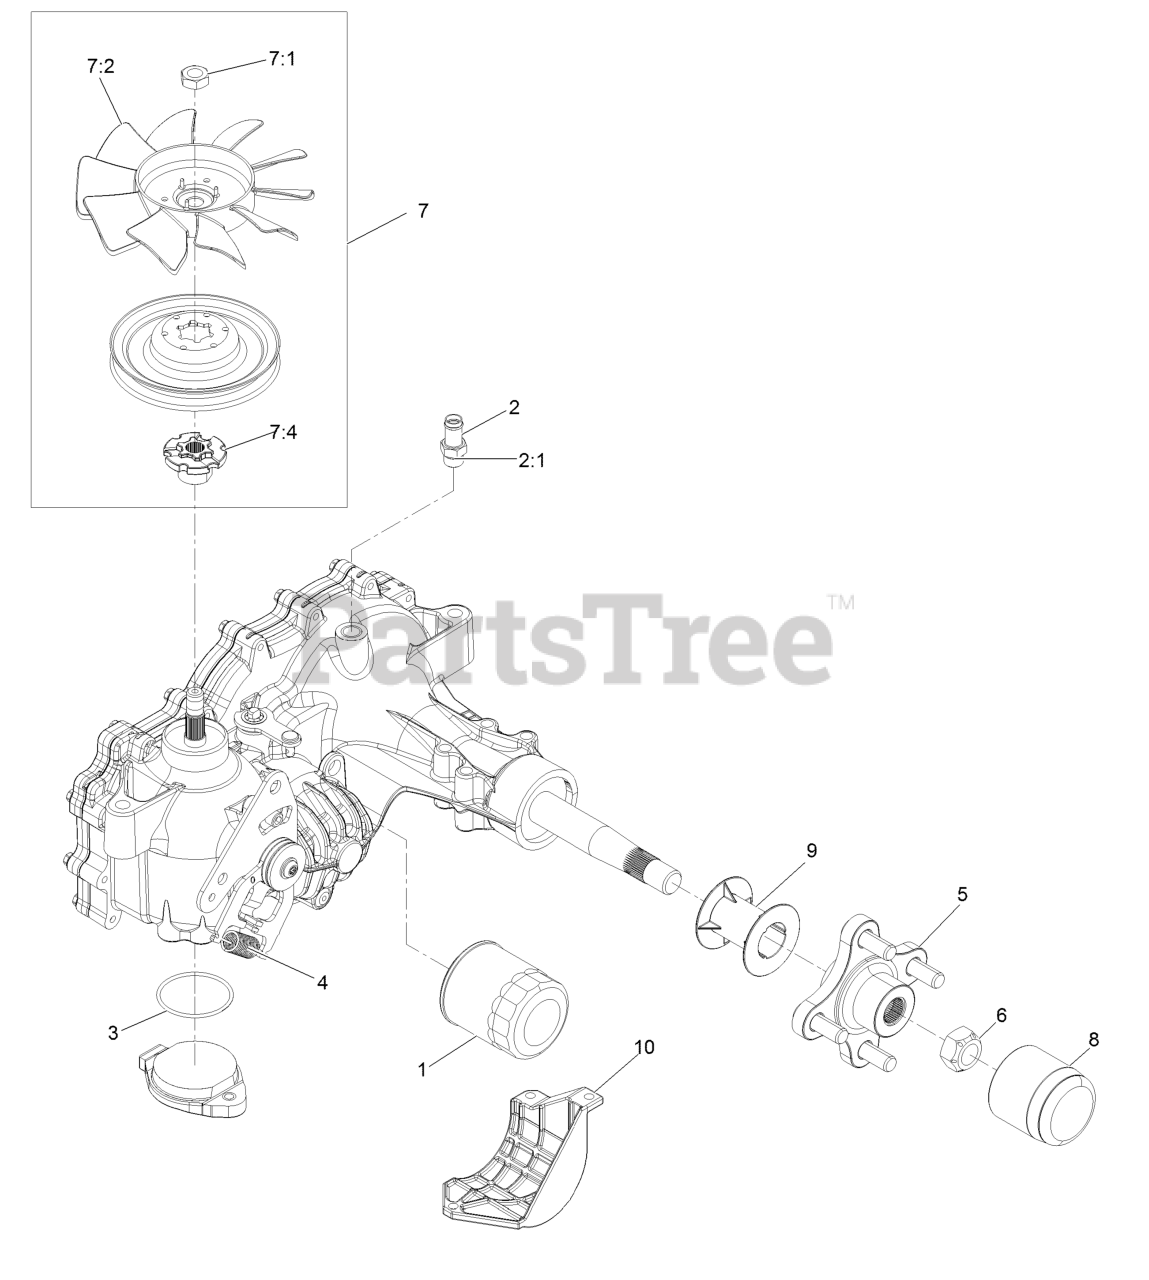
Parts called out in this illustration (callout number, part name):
1	Filter-Hydraulic
2	Adapter-Straight
2:1	O-Ring
3	O-Ring-Charge Seal Cover
5	Hub-Offset
6	Nut-Hub
7	Fan And Pulley Kit
7:4	Hub-Pulley
8	Cap-Axle, Long
9	Tube-Axle
10	Guard-Filter, LH
99	Seal Kit
